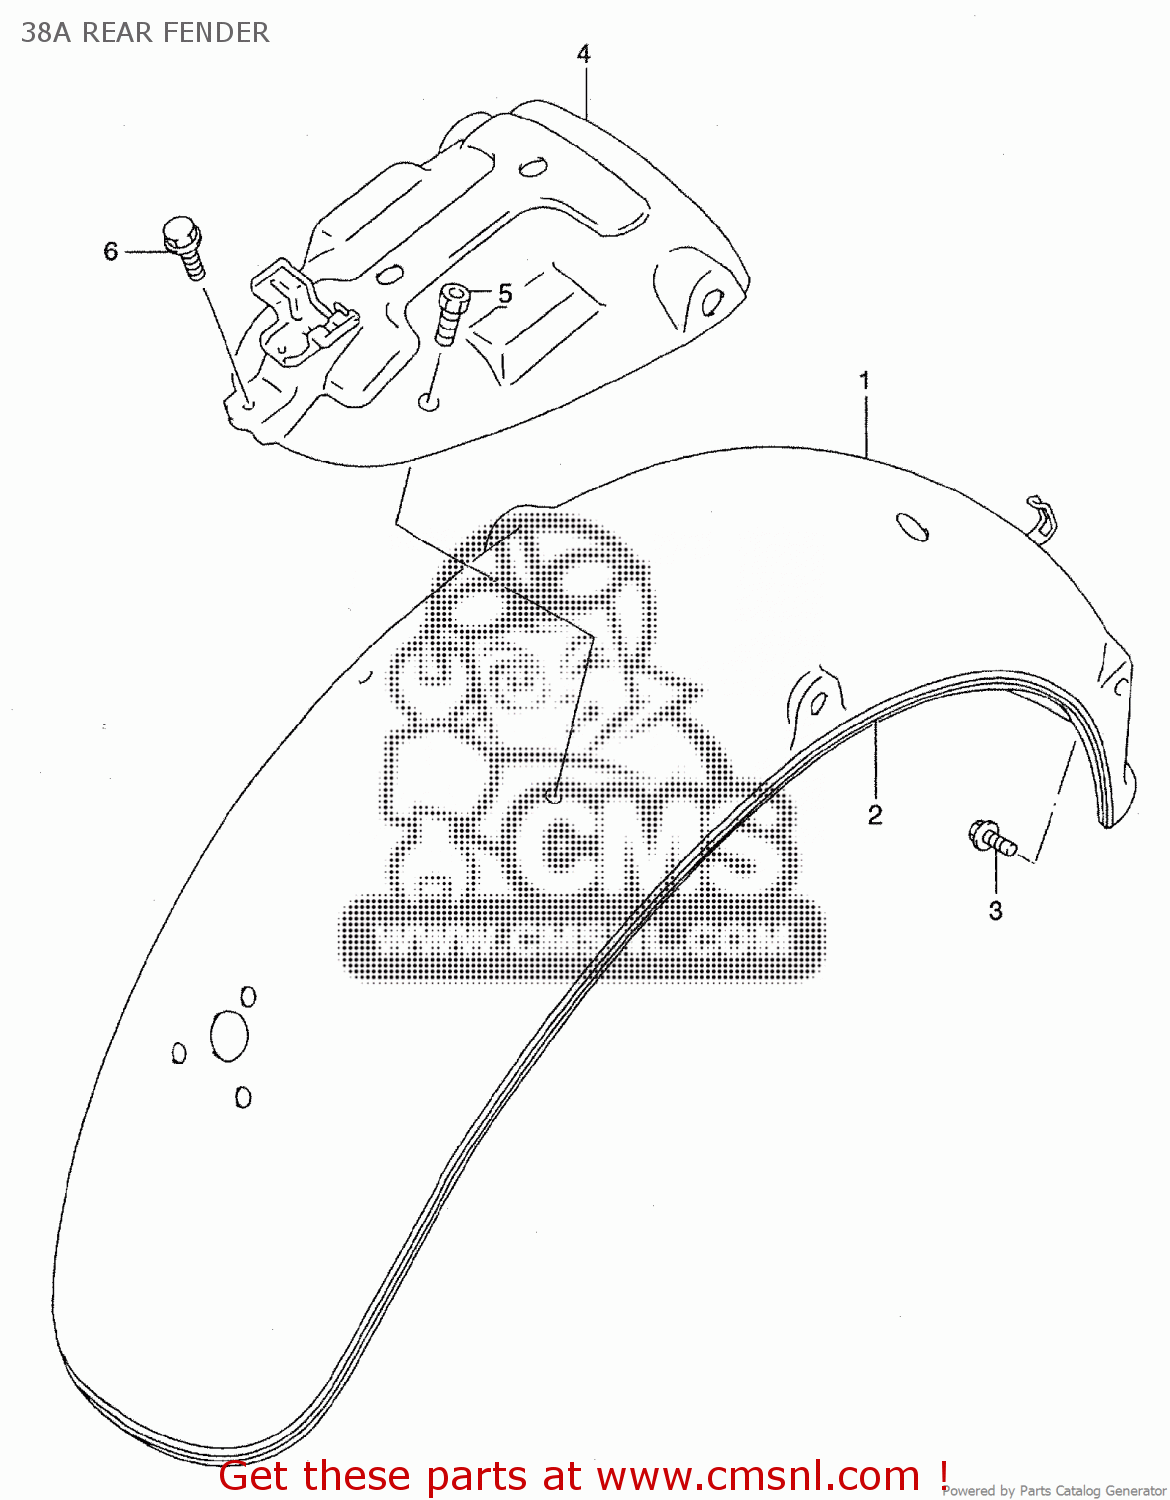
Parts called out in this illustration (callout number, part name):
1	FENDER ASSY,RR
3	BOLT
5	BOLT 6X16
6	SCREW(8X16)
